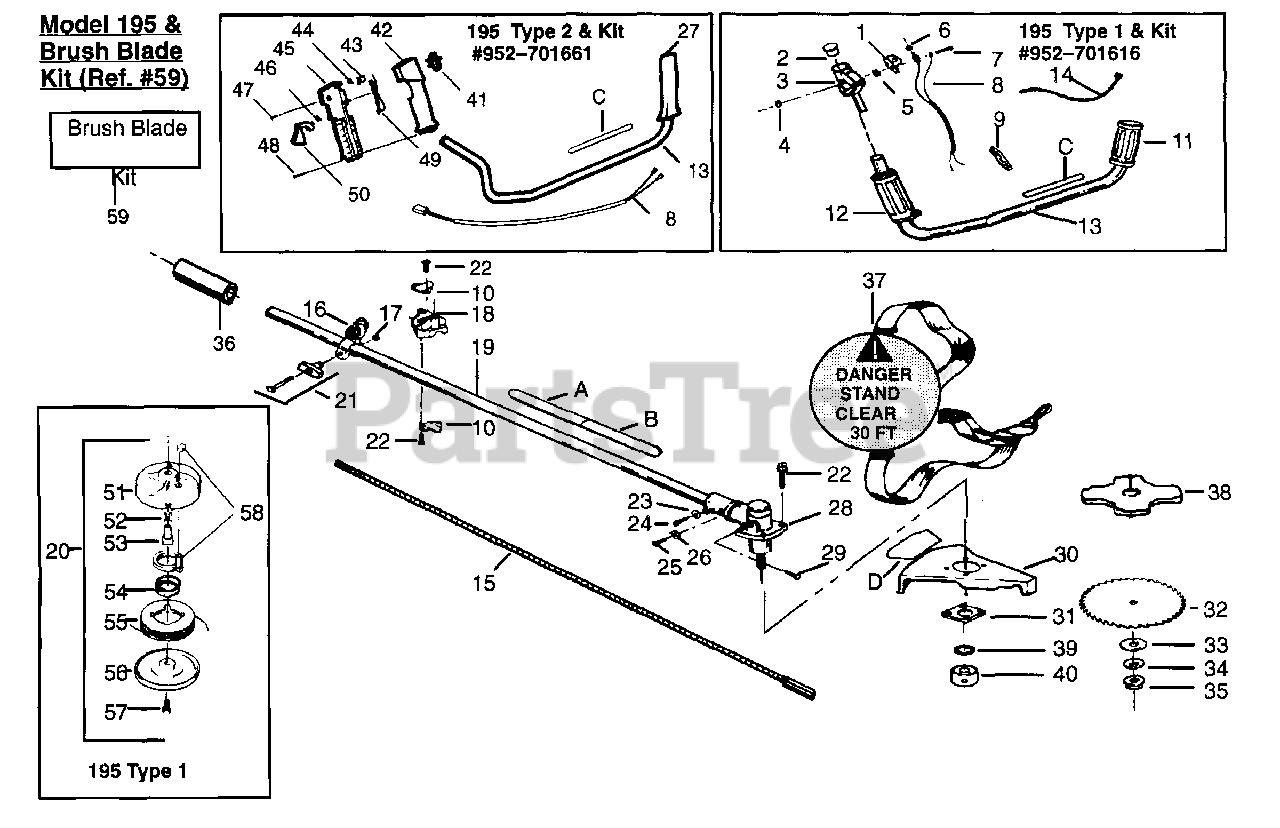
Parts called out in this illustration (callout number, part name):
1	Switch Bracket
2	Handlebar Cap
3	Throttle Lever Ass'y w/Lock(Incl 4 & 17)
6	Nut
9	Terminal Lock
10	Handlebar Backet
11	Handlebar Grip-Right
12	Handlebar Grip-Left
14	Tie Strap
15	Drive Shaft
16	Clamp-Harness Ass'y
18	Handlebar Clamp
19	Drive Shaft Housing
20	Twin Line Cutting Head
21	"T" Handle Ass'y
22	Screw (Use w/Metal Shield)
23	Lockwasher
26	Lockwasher
27	Grip-Handlebar-Type 2
28	Gear Box Ass'y
30	Metal Shield
31	Shield Retention Plate.
32	8" Brush Blade
33	Washer-Flat-Blade
34	Washer-Blade
35	Nut-Blade
36	Pad-Drive Shaft Hsg.
37	Shoulder Strap
38	4-Point Blade Optional
39	Seal-Gear Box
40	Dust Cup
41	Rocker Switch
42	Throttle Housing-Left
43	Throttle Lock
44	Throttle Spring
45	Throttle Housing - Right
46	Trigger Spring
49	Throttle Lockout
52	Line Saver
53	Drive Adaptor
55	Spool w/Line
58	Release Button Ass'y
59	Brush Blade Kit (Inc. 8, 10, 13, 16-19, 22, 27, 30, 31-37 & 41-50)
A	Warning-Upper
B	Warning-Lower
C	Handlebar Warning
D	Blade Direction (Not a serviceable part)
